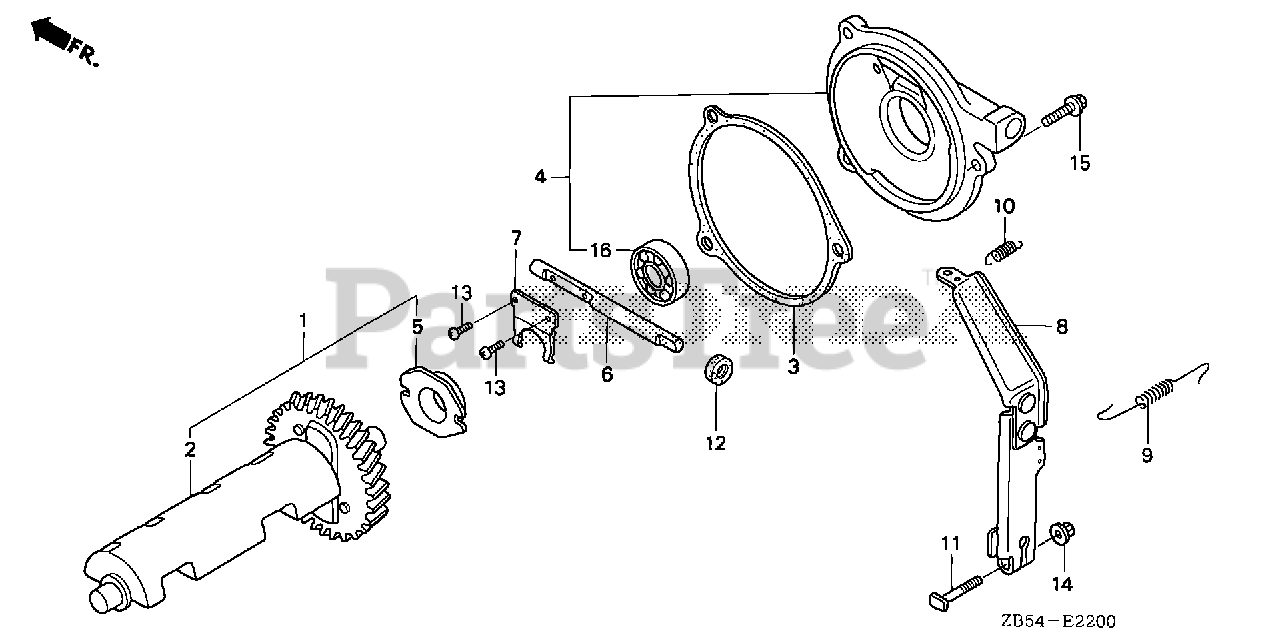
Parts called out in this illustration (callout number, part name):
1	GOVERNOR KIT
2	WEIGHT, BALANCER
3	GASKET, GOVERNOR COVER
4	COVER, GOVERNOR
5	SLIDER, GOVERNOR
6	SHAFT, GOVERNOR ARM
7	FORK, GOVERNOR
8	ARM, GOVERNOR
9	SPRING, GOVERNOR
10	SPRING, THROTTLE RETURN
11	BOLT, GOVERNOR ARM
12	OIL SEAL (8X14X5)
13	SCREW, PAN (3X8)
14	NUT, FLANGE (6MM)
15	BOLT, FLANGE (6X25)
16	BEARING, RADIAL BALL (6202)
